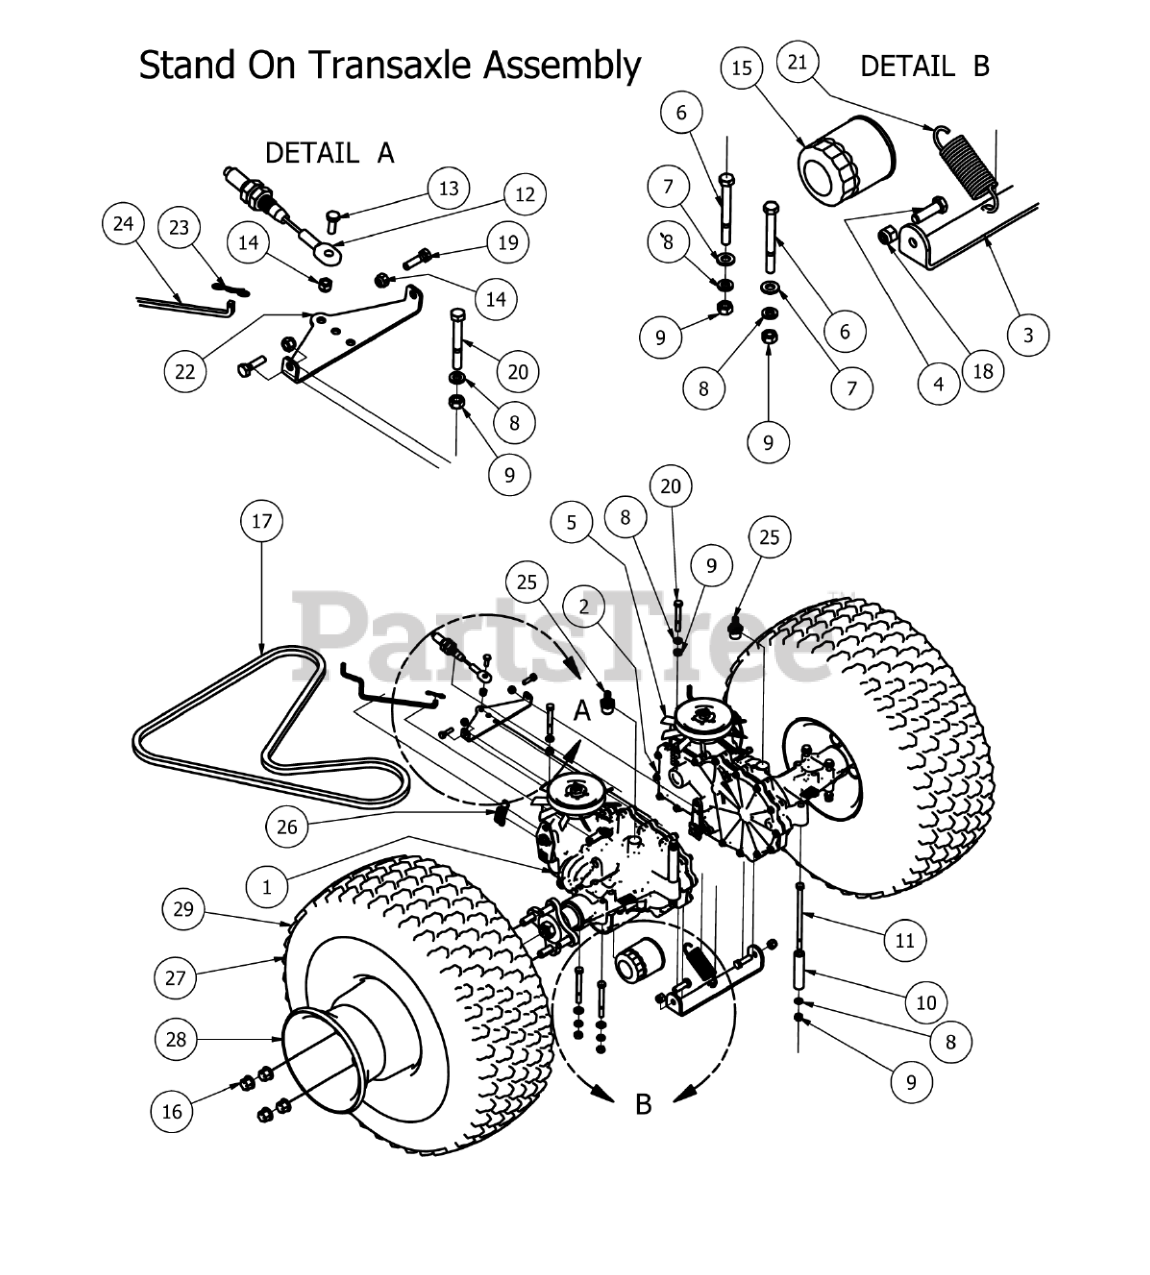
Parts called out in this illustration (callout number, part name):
1	Left 3400 IZT for CZT
2	Right 3400 IZT for CZT
3	Crossover Bar for ZT
4	3/8" x2" Hex Bolt
5	Fan/Pulley Kit For CZT
6	5/16" x 3" Hex Bolt
7	5/16" Flat Washer
8	5/16" Lock Washer
10	3 1/4" Spacer
11	5/16" x 6" Bolt
12	Brake Cable-Bandit Stand On
13	1/4" x 3/4" Hex Bolt
14	1/4" Nylock Nut
15	Transaxle Hydro Filter
16	Acorn Lug Nut
18	3/8 Nylock Nut
19	1/4-20 x 1 GR 5 hex bolt zinc
20	5/16" x 2 1/2" Bolt
22	Brake Bracket
24	MZ Brake Release Bar
25	45 degree fitting
26	Spring for Stand On Models
27	23 x 10.50 -12 Assembly W/Negative Offset Wheel
28	12 Orange Wheel
29	23 x 10.50-12 Tire
